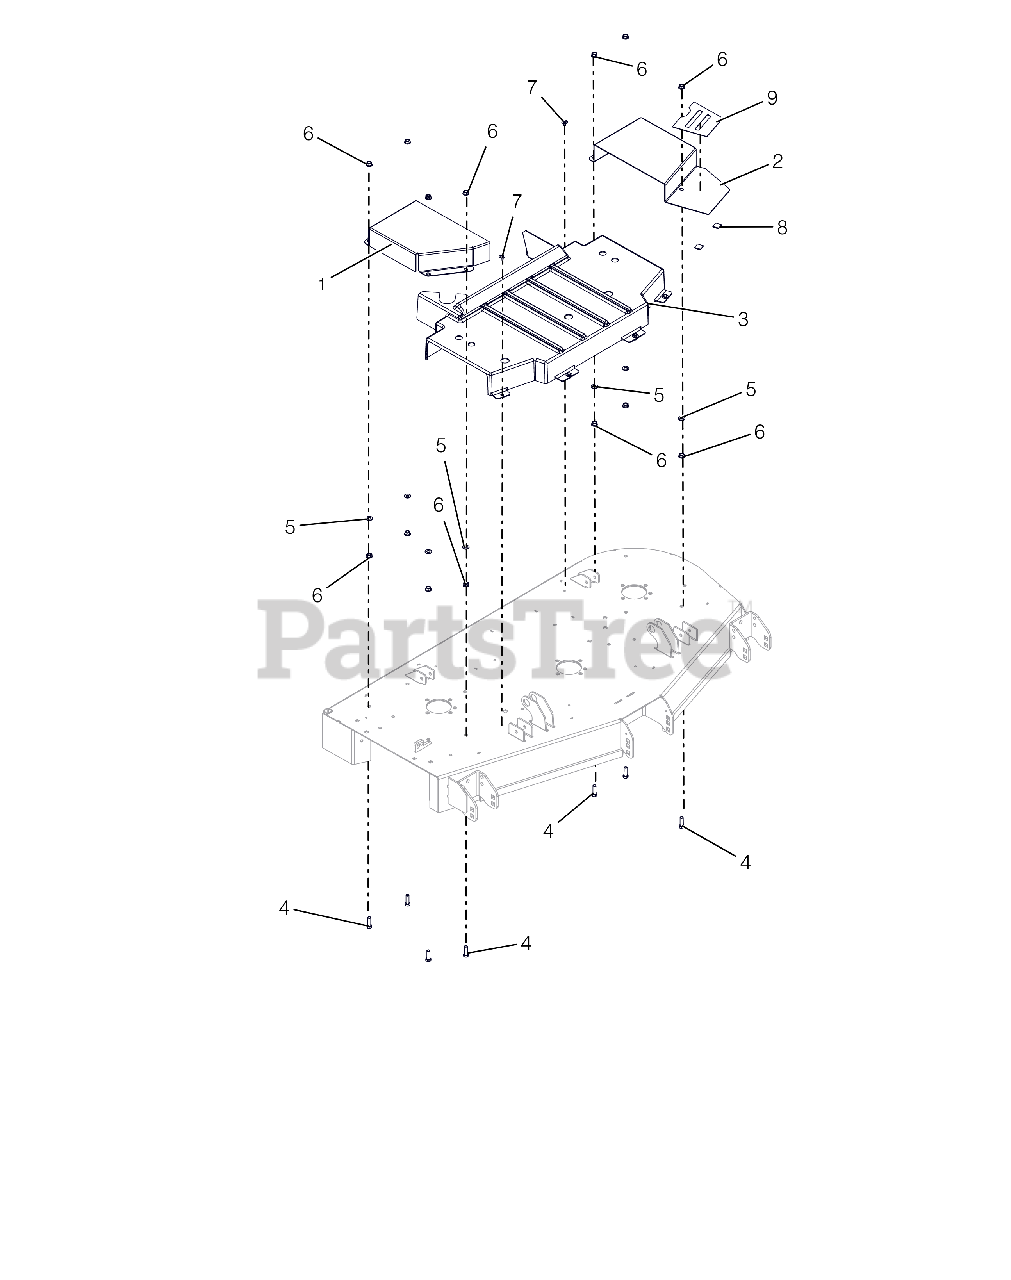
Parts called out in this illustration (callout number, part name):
1	GUARD,BELT 52" RIGHT CE
2	GUARD,BELT 52" LEFT CE
3	GUARD,CENTER,DECK SPINDLE CE
4	@BLT-HEX .38-16X1.25 GR5 YWZC
5	@WSHR-FL-STL.406X.812X.065 YWZ
6	@NUT-SPNLK-FLG .375-16 YWZC
7	SCR-TAP .25-20X.50 LGHWH TR YZ
9	GRIP TAPE 52-60 BELT COVER
